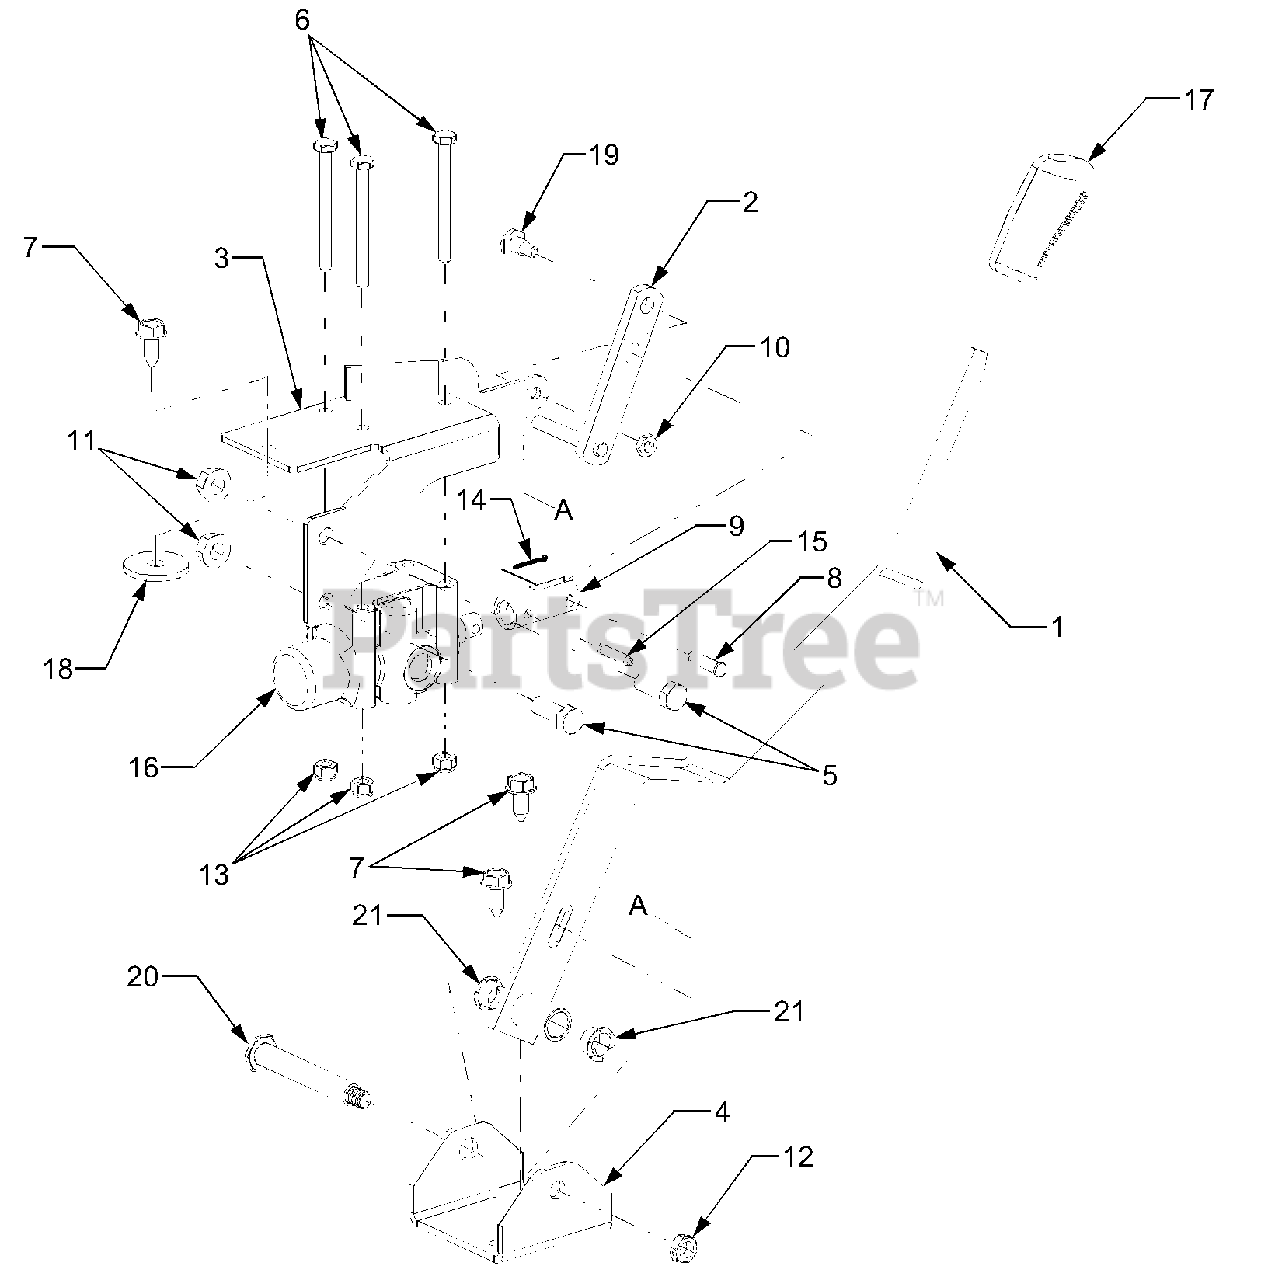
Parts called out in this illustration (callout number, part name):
1	Handle, Lift
2	Link, Valve
6	Screw, Hex Cap 1/4-20 x 2.75 GR5
7	Screw, Hex Wash, Hd Tapp 5/16-18 x .75
8	Pin, Clevis, .25 x .9375
9	Link, Valve
10	Nut, Hex Jam, 1/4-20
11	Nut, Hex Flange Top Lock, 3/8-16 GRF
12	Nut, Hex Ctr Lock Jam, 3/8-16
13	Nut, Hex Nylon Insert Lock 14-20 GR8
14	Pin, Cotter, 1/16 x .75
15	Pin, Spirol, 3/16 x 1.0
16	Valve, Hydaulic Lift
17	Grip, Handle
18	Washer, Flat, .385 x 1.0 x .135
19	Screw, Shoulder, .34 x .285
20	Screw, Shoulder, .498 x 2.99
21	Bearing, Nylon Flange .5 ID
